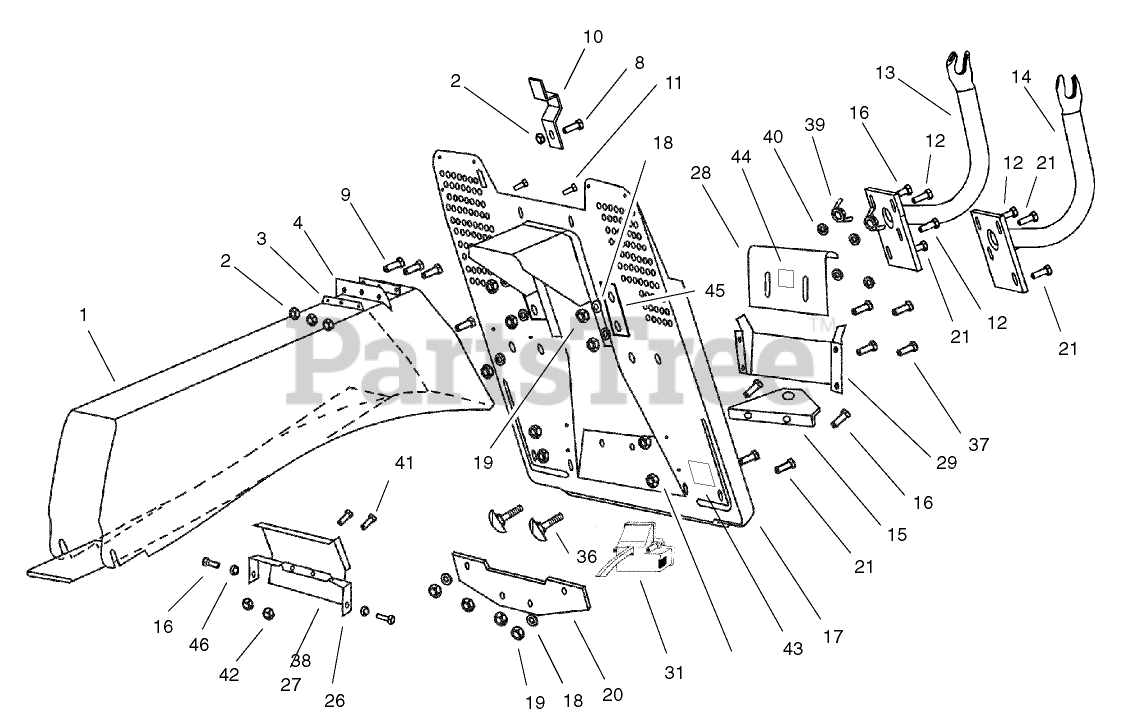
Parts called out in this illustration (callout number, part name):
1	TUNNEL
2	NUT-HEX
3	PLATE-SUPPORT
4	SEAL-RUBBER
9	SCREW-SFH
10	COVER-SWITCH
11	BOLT-CARRIAGE
13	SUPPORT-COLLECTOR, RIGHT
14	SUPPORT-COLLECTOR, LEFT
15	HITCH-TOW
16	SCREW-HEX
17	COLLECTOR PLATE ASM
18	WASHER-FLAT
19	NUT-LOCK, NI
20	SUPPORT-HITCH, TOW
21	SCREW-HEX
26	BRACKET-SHIELD, PROTECTIVE
27	SHIELD-PROTECTIVE
28	Shield-Adjustable
29	Hopper-Receiving
31	OVERLOAD SWITCH ASM
36	BOLT-CARR
37	SCREW-HH
38	NUT-LOCK
39	NUT-WING
40	WASHER-FLAT
41	BOLT-CARRIAGE
42	NUT-LOCK
43	DECAL-BYPASS, HYDRO
44	DECAL-POSITION, BAGGING
45	Plate-Reinforcing
46	Washer-Spring
